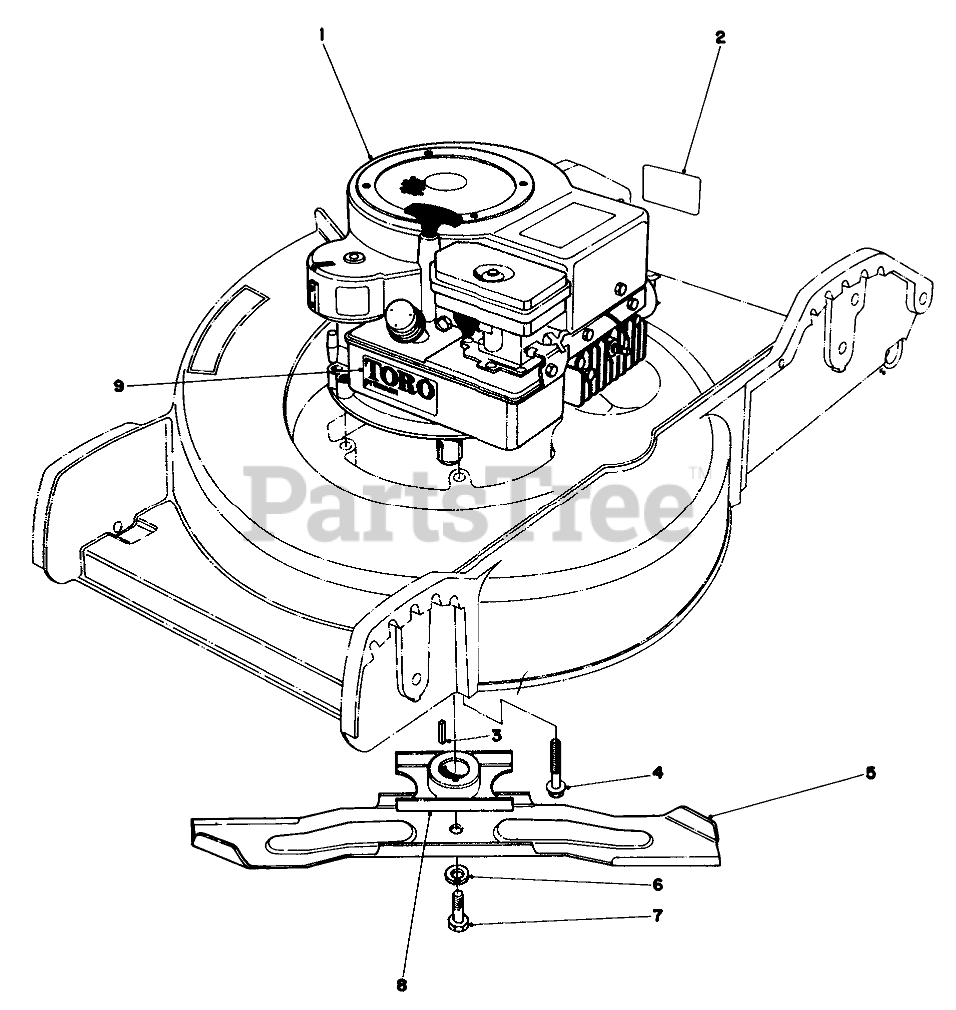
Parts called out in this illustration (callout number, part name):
1	Engine
2	Decal Maintenance
3	KEY-SQUARE
4	3/8-16 X 2 CAPSCREW
5	Blade
6	WASHER-LOCK
7	SPECIAL SCREW
8	Blade Retailer
9	Decal
